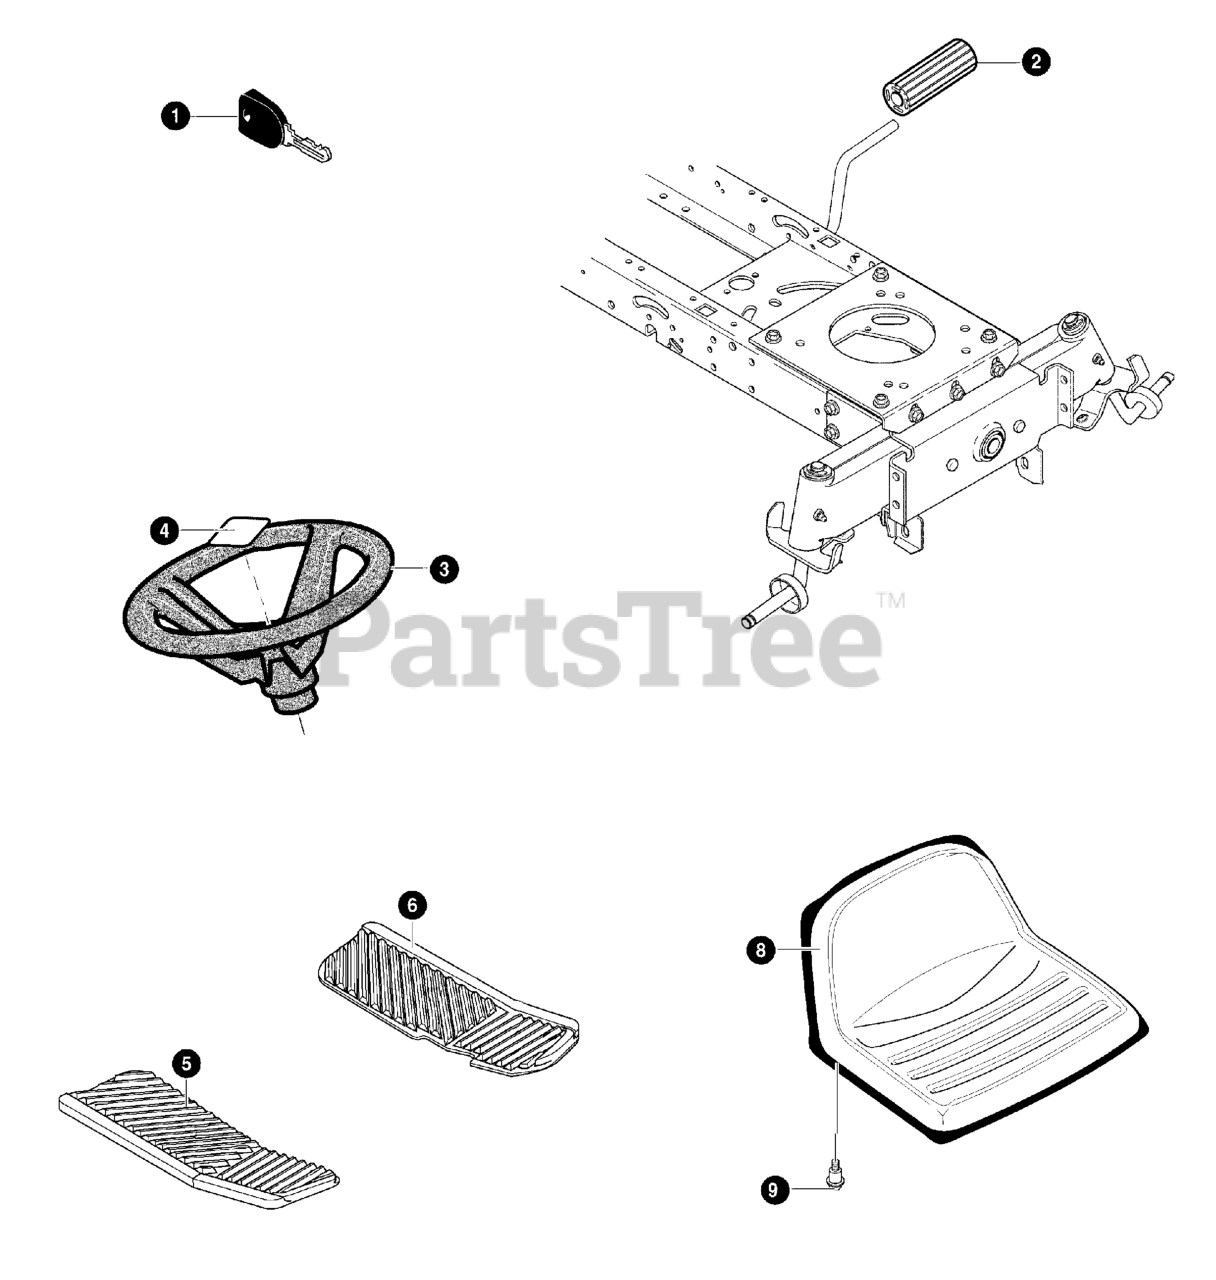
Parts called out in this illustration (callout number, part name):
1	KEY, IGNITION
2	COVER, PED, BRAKE
3	STEERING WHEEL
4	INSERT, 4-SPOKE
5	FOOTPAD, RH
6	FOOTPAD, LH
8	SEAT, FAUL HI-BACK
9	BOLT, SHOULDER 5/16-18
